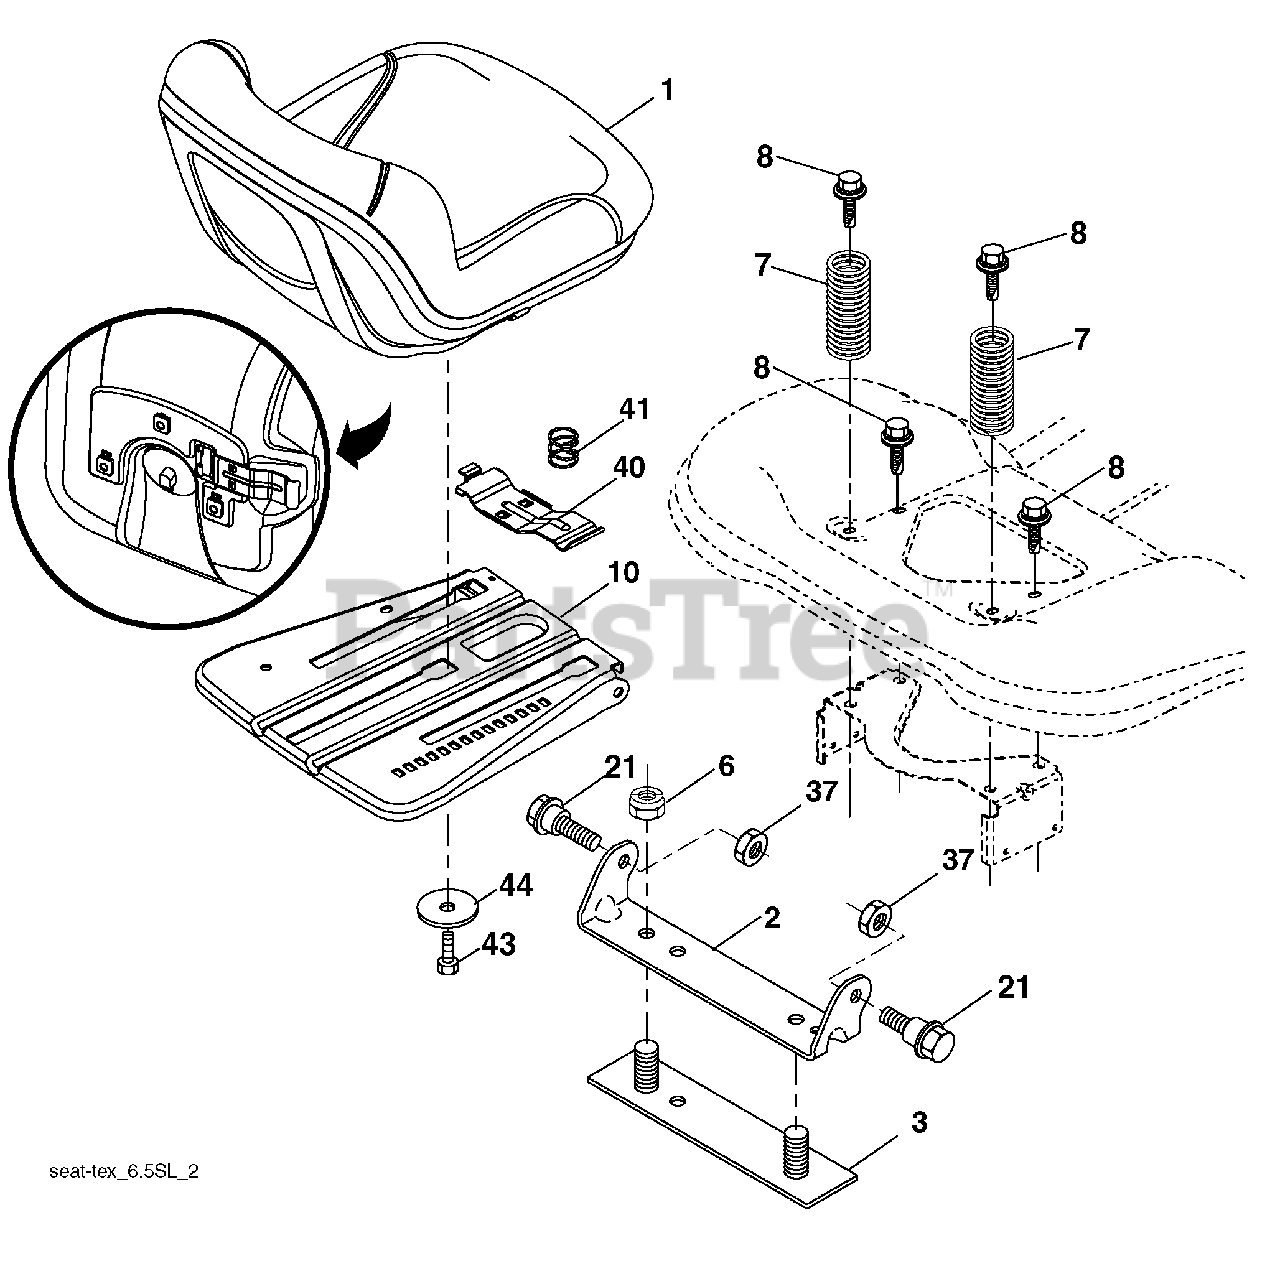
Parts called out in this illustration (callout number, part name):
1	Seat
2	Bracket Pivot Fender
3	Strap, Asm Fender
6	Nut, Lock W/Ins. 3/8-16 Unc
7	Spring, Seat Cprsn
8	Bolt 5/16-18 Unc X 3/4 W/Sems
10	Pan, Seat
21	Bolt, Shoulder 5/16-18
37	Nut, Lock 5/16-18 Unc
40	Handle Slide Seat
41	Spring Latch Seat
43	Bolt Fin Hex 3/8-16 Unc X 3/4
44	Washer 13/32 X 2-3/8 X 12 Ga.
